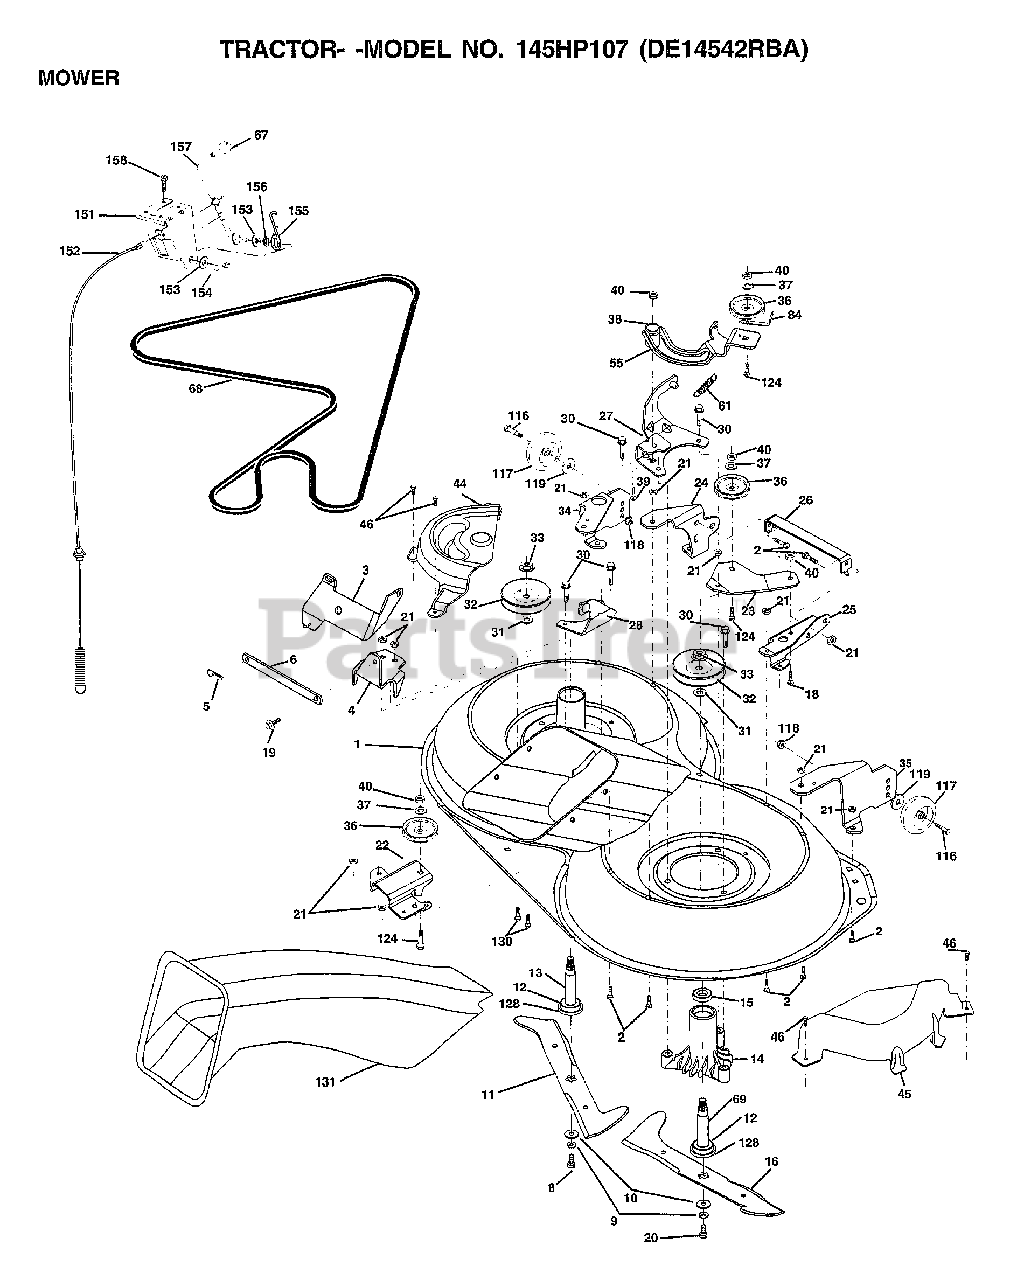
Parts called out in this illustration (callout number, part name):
1	HOUSING ASM MOWER
2	BOLT
3	BRKT.ASM.S-BAR.CHASSIS
4	BRKT BAR SWAY DECK
6	BAR.SWAY.92.CRD
8	BLADE BOLT
10	WASHER.HARD.BLADE
12	BEARING.BALL
14	HSG ASM MANDREL
15	BEARING
16	BLADE
18	BOLT D
19	BOLT SHD 5/16-18
20	BOLT.3/8-24X1.25
22	BRKT IDLER SPRT
23	BRKT IDLER SPRT
24	BRKT SUSPENSION
25	BRKT SUSPENSION
26	BRACE.SUPT.SUSP.FRT.CRD
27	BRKT ASM SUSP
28	BRKT ASM SUSP
30	"SCREW-THD ROLL,WA"
31	WASHER
32	PULLEY.MANDREL.42
34	BRKT GAUGE WHEEL
35	BRKT GAUGE WHEEL
36	PULLEY.IDLER.4.25
37	WASHER
38	SPACER HUB ARM IDLER
39	BOLT
44	COVER MANDREL
45	COVER MANDREL
46	SCREW.1/4-20X5/8
55	ARM IDLER
61	SPRING.TENSION.BELT
67	KNOB T(3/8 HOLE)
68	HEX-BELT
69	SHAFT.ASM.W/LWR.BRG.RH.THD
84	"KEEPER-BELT,IDLER"
116	BOLT.SHOULDER
117	WHEEL GAGE DONUT
118	LOCKNUT
119	WASHER
124	BOLT.3/8-16X1.50
128	WASHER.FELT.
131	CHUTE.BAGGER.CRD
151	BRKT CLUTCH CABLE
152	CABLE CLUTCH CRD SERVICE
153	WASHER FLAT
154	SPRING RETAINER
155	SPRING RETENTION LVR CLUTCH CAB
156	SPACER
157	ROD.CLUTCH.CABLE.3/8
158	SCREW LT
